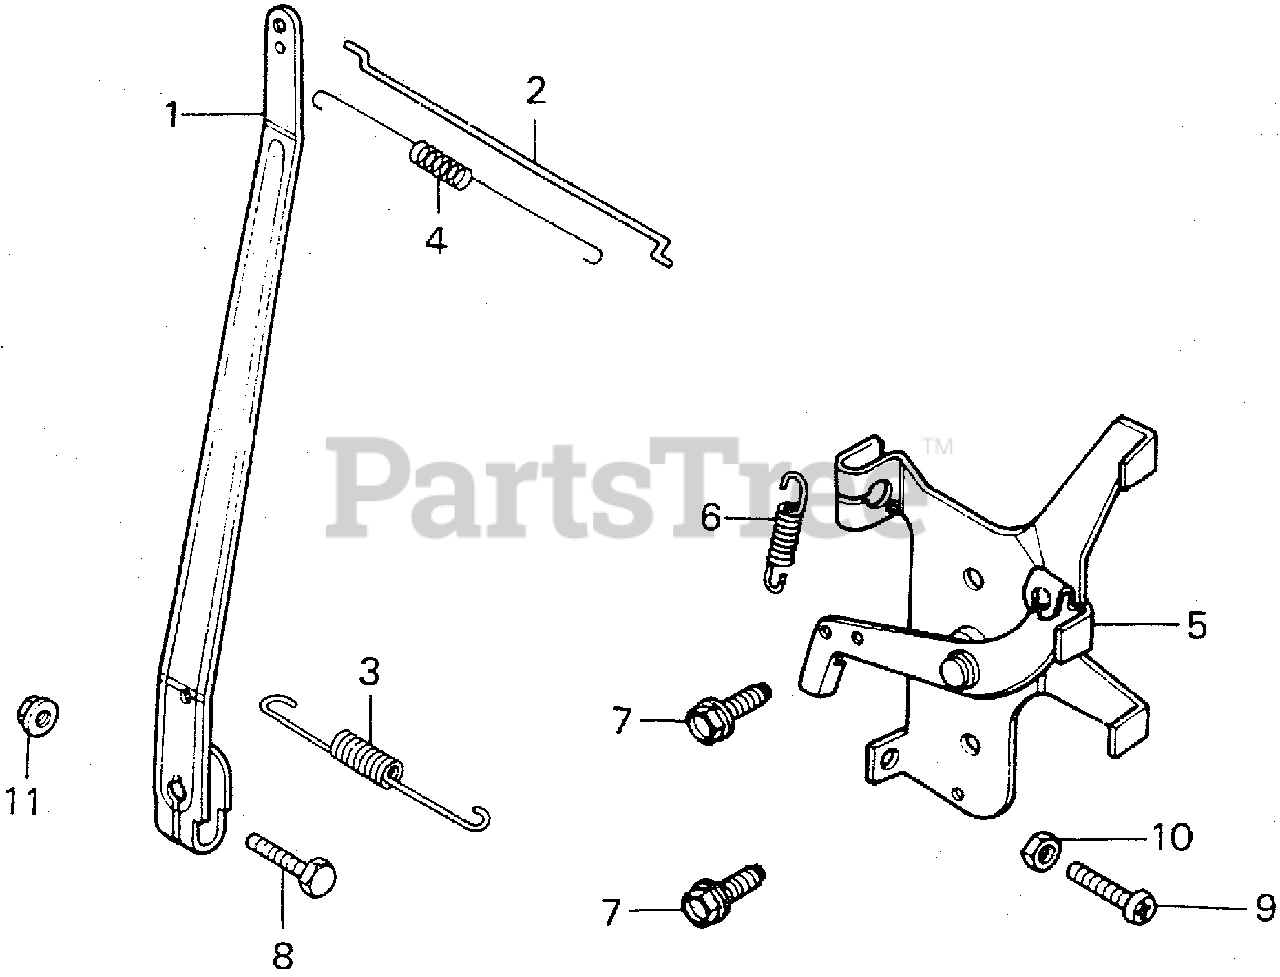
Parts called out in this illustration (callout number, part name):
1	ARM, GOVERNOR
2	ROD, GOVERNOR
3	SPRING, GOVERNOR
4	SPRING, THROTTLE RETURN
5	LEVER, CONTROL
6	SPRING, CABLE RETURN
7	BOLT, FLANGE (6X12) (CT200)
8	BOLT, HEX. (6X20)
8	BOLT, HEX. (6X25)
9	SCREW, PAN (6X20)
10	NUT, HEX. (6MM)
11	NUT, FLANGE (6MM)
